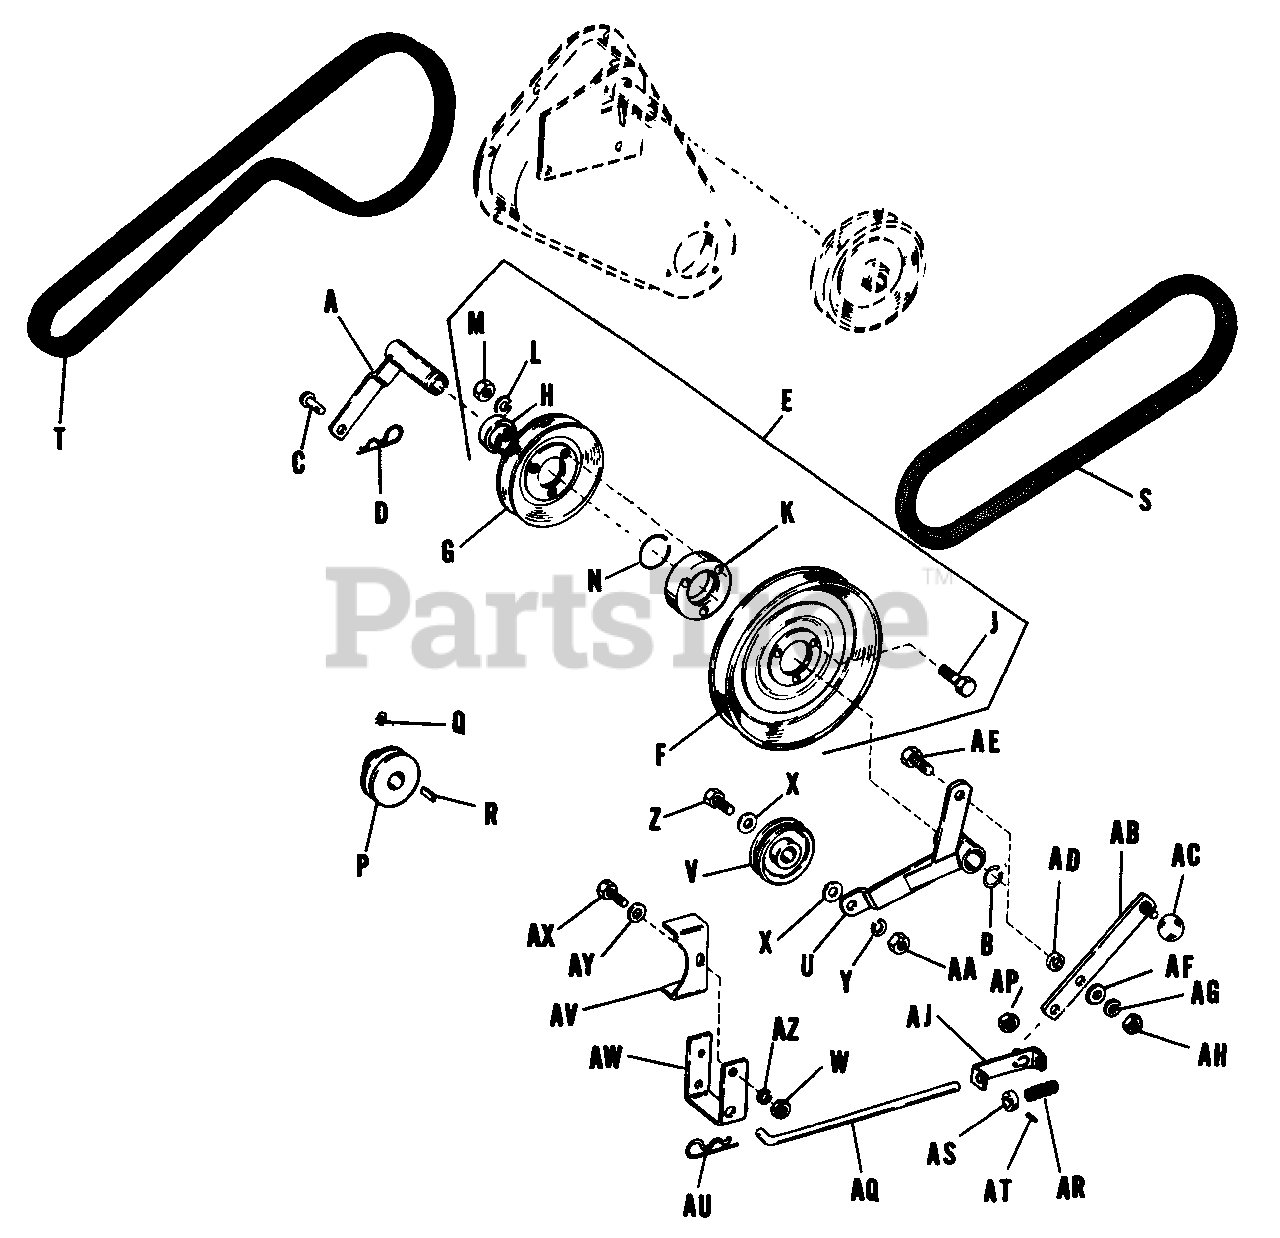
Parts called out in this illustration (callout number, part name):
A	Sleeve Assembly Pulley
B	Ring, Snap
D	Clip, Spring
E	Pulley Assembly
F	Pulley, 10"
G	Pulley, 5 1/2"
J	Capscrew, Hex., 5/16"-18 NC x 13/4" lg.
L	Washer, Lock, 5/16"
M	Nut, Hex, Full, 5/16"-18 NC
N	Ring, Snap
P	Pulley, Tiller Drive
Q	Screw, Set, Cup Point, Socket Head, 5/16"-18 NC x 5/16" lg.
T	Belt,"V" (105280 BELT FOR 3012)
U	Lever Assembly, Idler
V	Pulley, Idler
W	Nut, Hex, Full, 3/8"-16 NC
X	Washer, Plain, 5/16"
Y	Washer, Lock, 3/8"
Z	Capscrew, Hex, 3/8"-16 NC x 1 1/4" lg.
AA	Nut, Hex, Full, 3/8"-16 NC
AB	Lever Assembly, Clutch
AE	Capscrew Hex, 3/8"-16 NC x 1" lg.
AF	Washer, Plain, 3/8"
AG	Washer, Lock, 3/8"
AH	Nut, Hex, Full, 3/8"-16 NC
AJ	Guide Assembly
AK	Capscrew, Hex, 3/8"-16 NC x 7/8" lg.
AM	Washer, Plain, 3/8"
AN	Washer, Lock, 3/8"
AP	Hex Nut, Full, Lock, 5/16"-18
AQ	Rod Short for 10 H.P.-105282 Long for 12 H.P.
AS	Collar, Set
AT	Screw, Set, Square Head, Cup Point, 1/4"-20 NC x 3/8" lg.
AU	Clip, Spring
AV	Release, Belt
AW	Bracket, Belt Release
AX	Capscrew, Hex, 3/8"-16 NC x 7/8" lg.
AY	Washer, Plain, 3/8"
AZ	Washer, Lock, 3/8"
